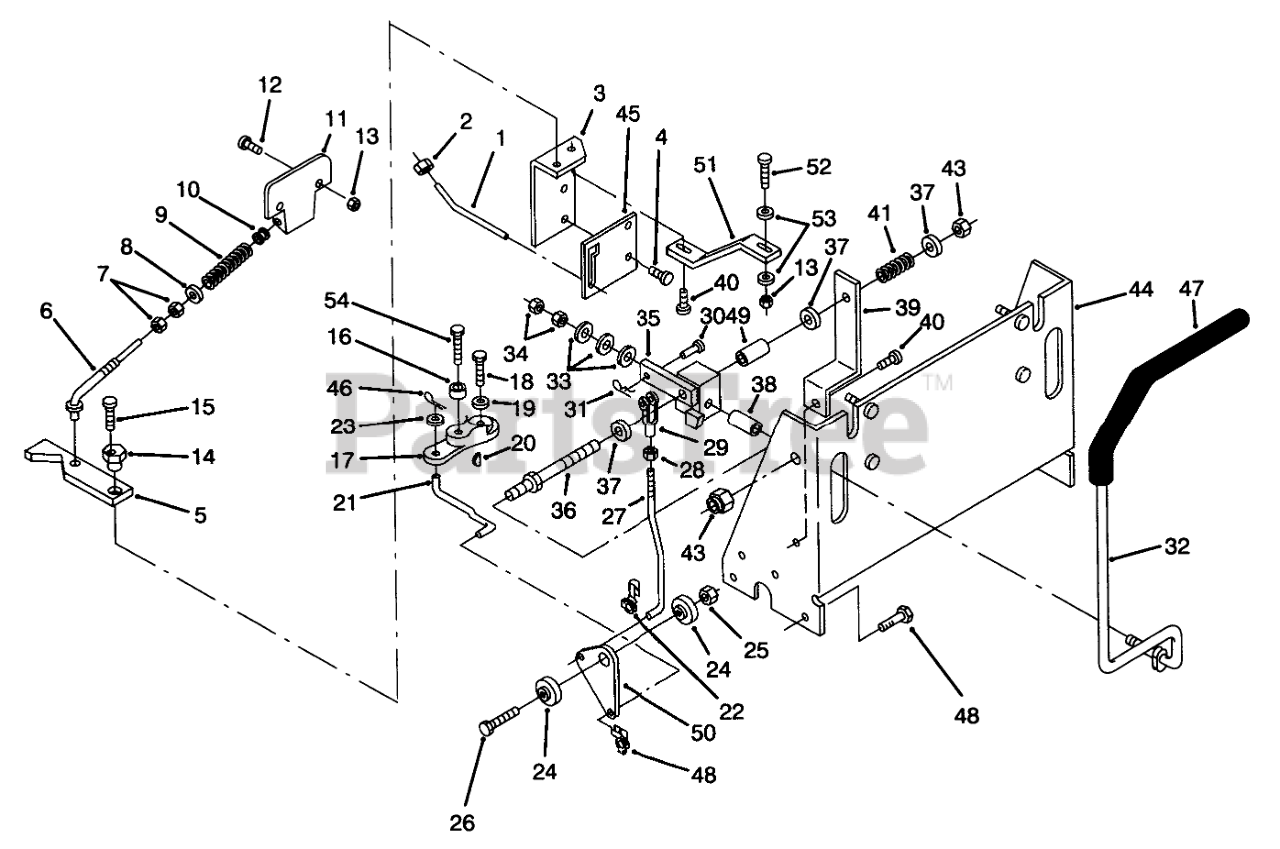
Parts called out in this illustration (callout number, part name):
1	LEVER-TOW VALVE
2	NUT-LOCK, NI
3	Bracket RH
4	SCREW-TAPTITE
5	Arm
6	ROD-NEUTRAL RETURN
7	NUT-JAM
8	WASHER-FLAT
9	SPRING COMPRESSION
10	NYLINER BUSHING
11	Bracket
12	SCREW-HSH
13	NUT-LOCK, NI
15	Bolt
16	SPACER
17	Arm-Control, RH
18	Bolt
19	WASHER-FLAT
20	KEY WOODR 1/8X1/2 DI
21	LINK-R.H.
22	CLIP-CLEVIS L.H.
23	WASHER-FLAT
24	SPACER-CLUTCH LINK
25	NUT-LOCK, NI
26	SCREW-HH
27	ROD-HYDRO CTRL. ADJ.
28	NUT-JAM
30	Pin
32	R/H STRG LEVER B
33	SPRING-BELLVILLE
34	NUT-JAM
35	Lever Pivot RH
36	SHAFT-PIVOT
37	WASHER-FLAT
38	BUSHING-STR LVR PVT
39	Bracket-Retainer
40	SCREW-HWHTF
41	SPRING
43	NUT-LOCK, NI
44	Lever Support
45	PLATE-TOW VALVE L
46	PIN-COTTER
47	Grip
48	CLIP-CLEVIS R.H.
49	BUSHING
50	PLATE-CONTROL PIV
51	Bracket-RH
52	SCREW-HH
53	WASHER-PLAIN
54	SCREW-HH
